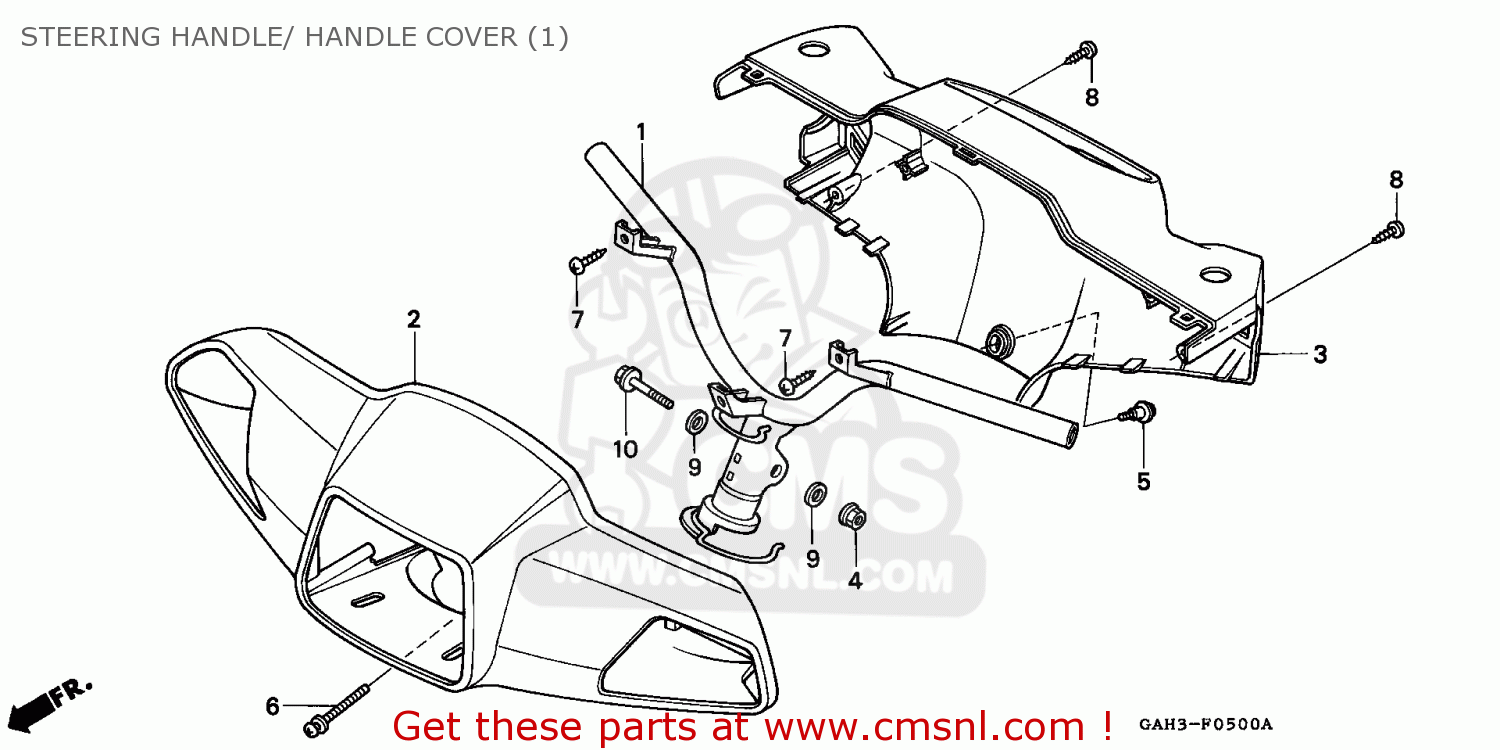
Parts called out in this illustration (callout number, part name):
1	HANDLE COMP.,STEE
2	COVER FR. HANDLE
3	COVER,RR.H*G120R*
4	NUT,U,FLANGE,10MM
5	SCREW,PAN,5X7
6	SCREW WASHER,5X28
7	SCREW,TAP 4X12
8	SCREW,4X12
9	WASHER,10MM
10	BOLT,FLANGE,10X43
